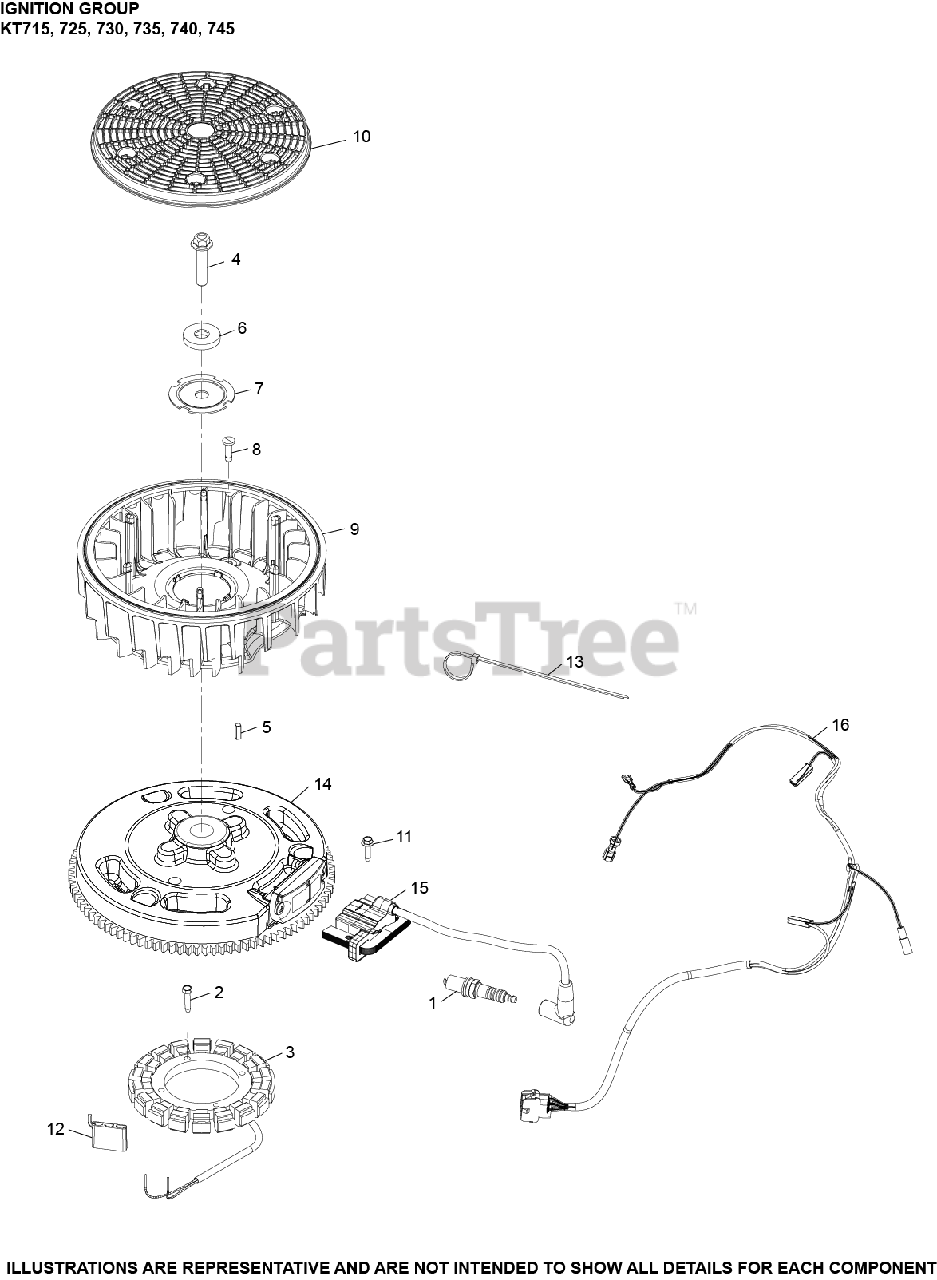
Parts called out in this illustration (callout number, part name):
1	PLUG, SPARK (STD)
2	SCREW, THREAD FORMING
3	KIT, 15 / 20 AMP STATOR
4	SCREW, HEX FLANGE
5	KEY, SQUARE
6	WASHER, FLAT
7	PLATE, FAN MOUNTING
8	RETAINER, FLYWHEEL FAN
10	SCREEN, GRASS
11	SCREW, THREAD FORMING - USE 25 086 473-S
12	CONNECTOR
13	TIE, WIRE
14	FLYWHEEL ASSEMBLY
15	MODULE, IGNITION
16	HARNESS, WIRING ASSEMBLY
